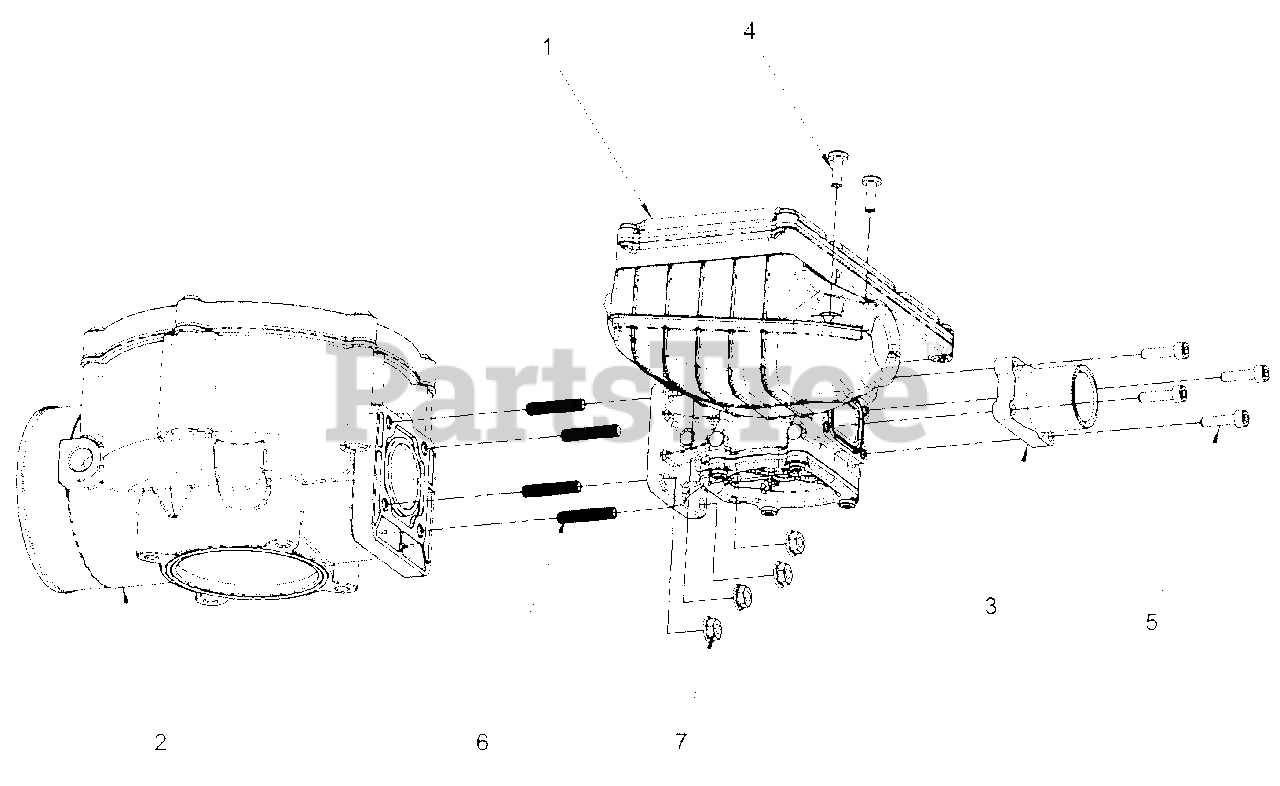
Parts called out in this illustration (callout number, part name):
4	SCREW, TAB
5	BOLT
6	STUD
7	NUT
